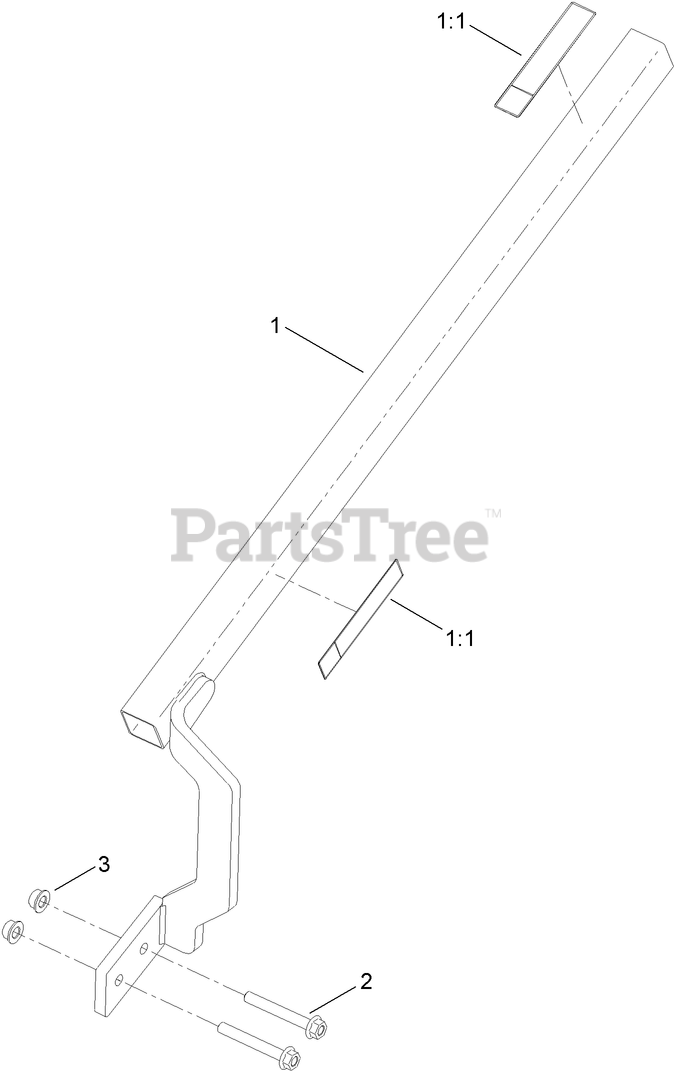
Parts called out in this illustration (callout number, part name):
1	48 INCH RESTRAINT BAR ASM
1:1	DECAL-DANGER, ENTANGLEMENT
3	NUT-HHF
